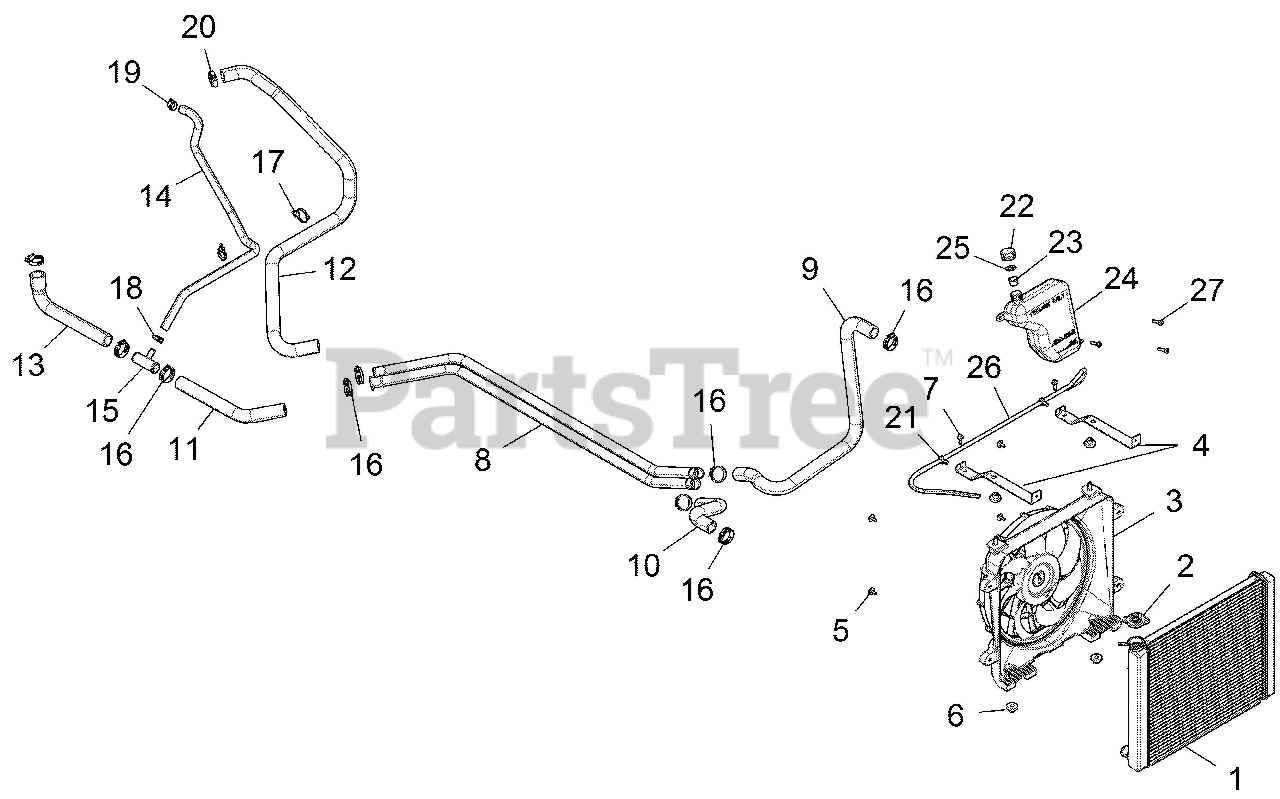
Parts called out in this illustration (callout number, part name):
1	ASM-RADIATOR,CORE
3	FAN-ASSEMBLY
4	MOUNT, RADIATOR, BLACK
5	BOLT-M6X15MM
7	SCR-M6X1.0X20,HXHD,FLG,TDFM,BL
8	TUBE-COOLANT,1"
9	HOSE-UPPER,RAD
10	HOSE-LOWER,RAD
11	HOSE-ENG,IN
12	HOSE-ENG,OUT
13	HOSE-ENG,INLET/BYPASS
14	HOSE-BYPASS
15	CONNECTOR-TEE,1X1X0.5
16	CLAMP,SPRINGBAND 35/12,BLK
17	CLIP-ROUTING
18	CLAMP-HOSE,SPRING,20MM
19	CLAMP, HOSE (10)
20	CLAMP-HOSE(WORM DR)25-40MM
22	CAP, OVERFLOW
23	CAP,PLUG9X(GRN),FLEX TEMP(10)
24	TANK-SURGE
25	GASKET (10)
26	FUEL LINE-95 CENTIMETERS
27	SCR-#14X1 HI/LO-PH-PN TRX-M
